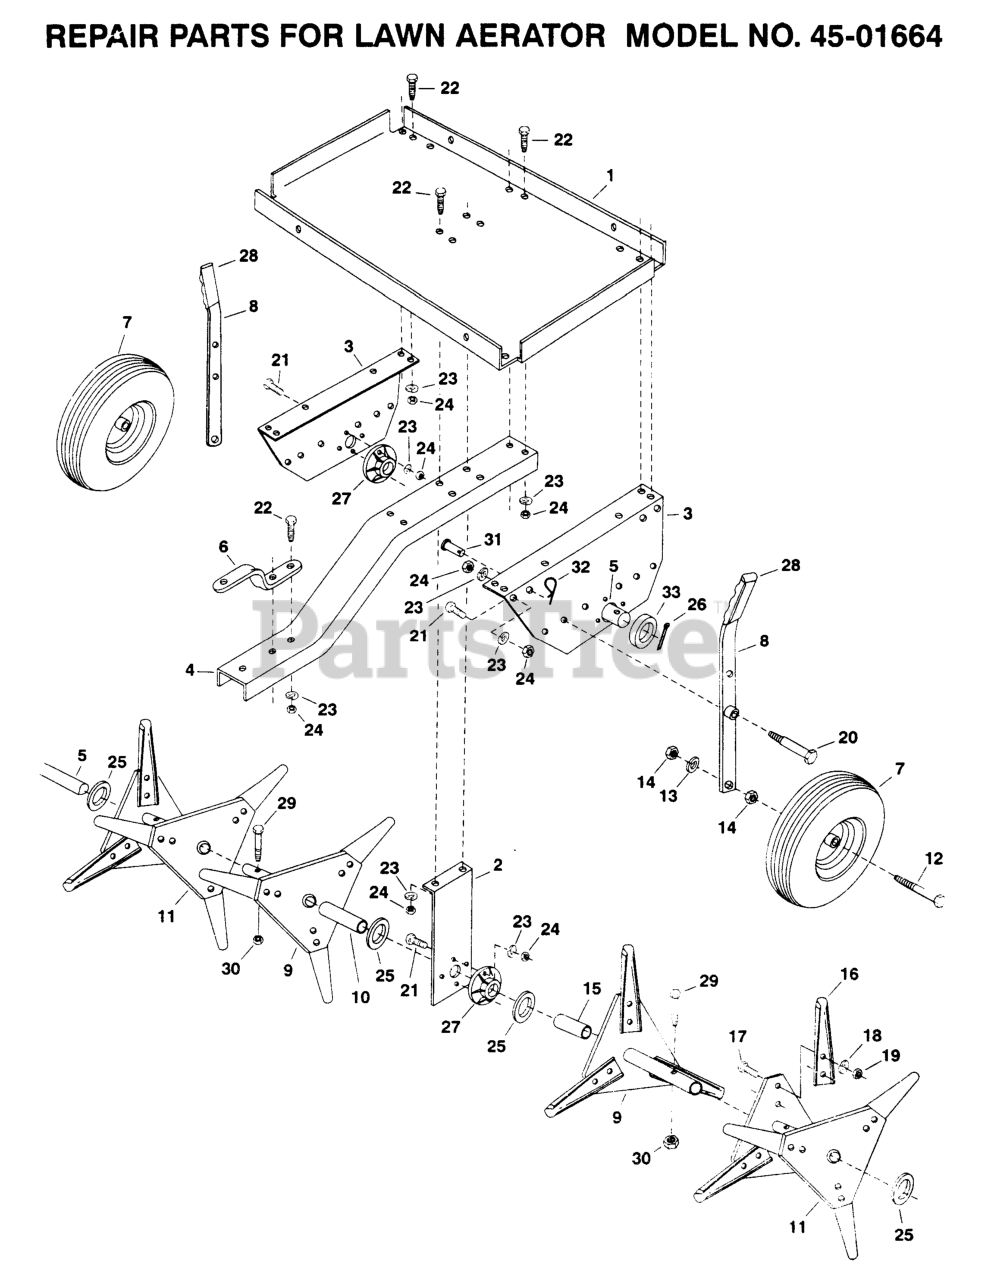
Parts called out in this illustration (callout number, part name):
6	Bracket, Hitch
17	BOLT.FIN.HEX.5/16-18X3/4
21	HEX BOLT
22	BOLT
23	Spring Washer
25	Washer, Flat 1-1/8" x .78" x .025"
29	SCREW M6S 6X30
